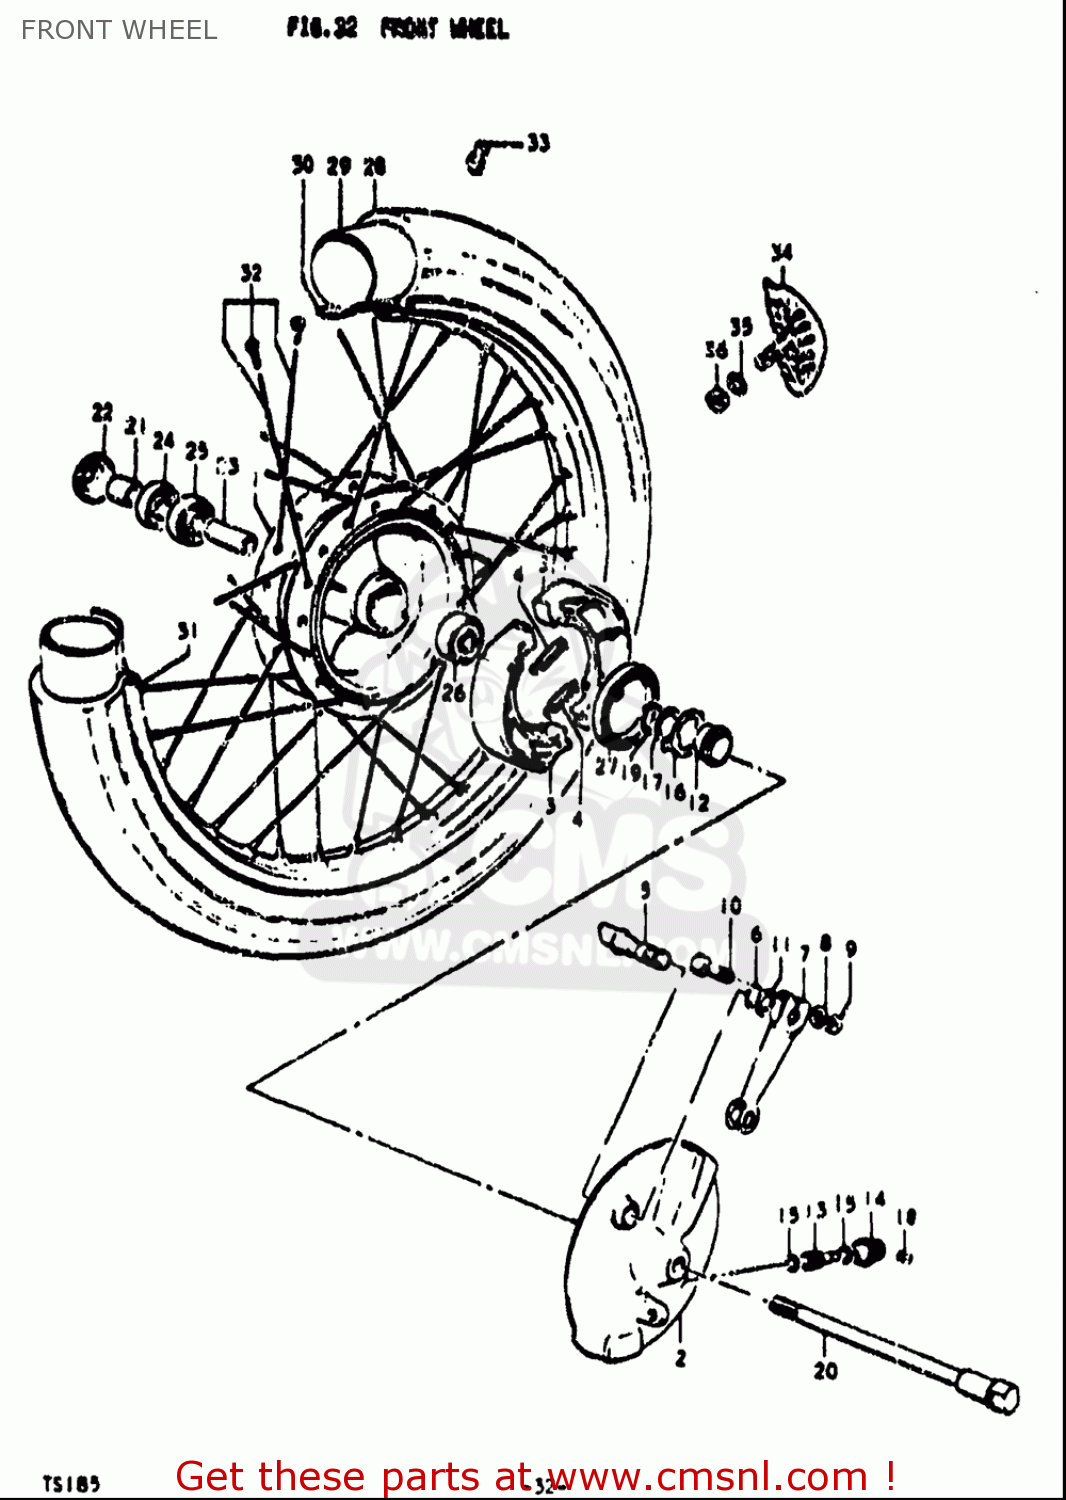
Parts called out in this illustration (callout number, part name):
3	SHOE & SPRING SET,BRAKE (NAS)
4	SPRING(L:35.8)
5	CAM,FR BRAKE
6	O RING(D:2.5,ID:11.4)
7	LEVER,FR BRAKE CAM
8	WASHER
9	NUT
10	BOLT(6X31)
11	WASHER(12.5X20X1)
15	WASHER(5.1X9X0.4)
16	DRIVER,SPEEDOMETER GEAR
17	WASHER(18.5X24X1)
18	SCREW
19	CIRCLIP
21	SPACER(12X18X16.4)
22	DUST SEAL,FRONT HUB DRUM
23	SPACER(12.5X19X52)
24	SEAL,OIL(18X32X7)
25	BEARING
26	BEARING
27	SEAL,OIL(43X58X7)
30	PROTECTOR,WHL INR TUBE
33	BALANCER,WHEEL (30G)
34	STOPPER,BEAD
35	WASHER
36	NUT
